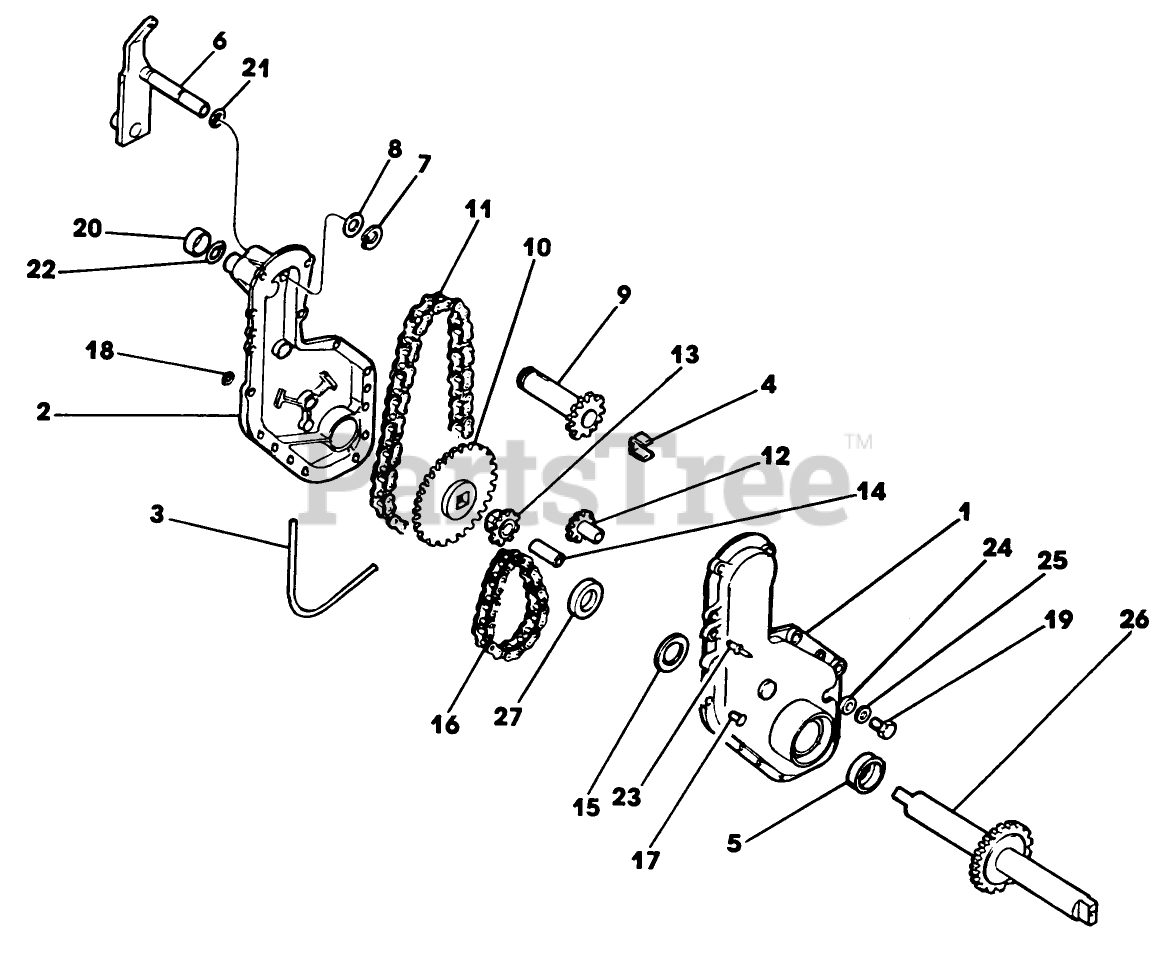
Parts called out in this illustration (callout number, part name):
6	IDLER ARM ASSEMBLY
10	SPROCKET
12	IDLER-SPROCKET
13	SPROCKET
